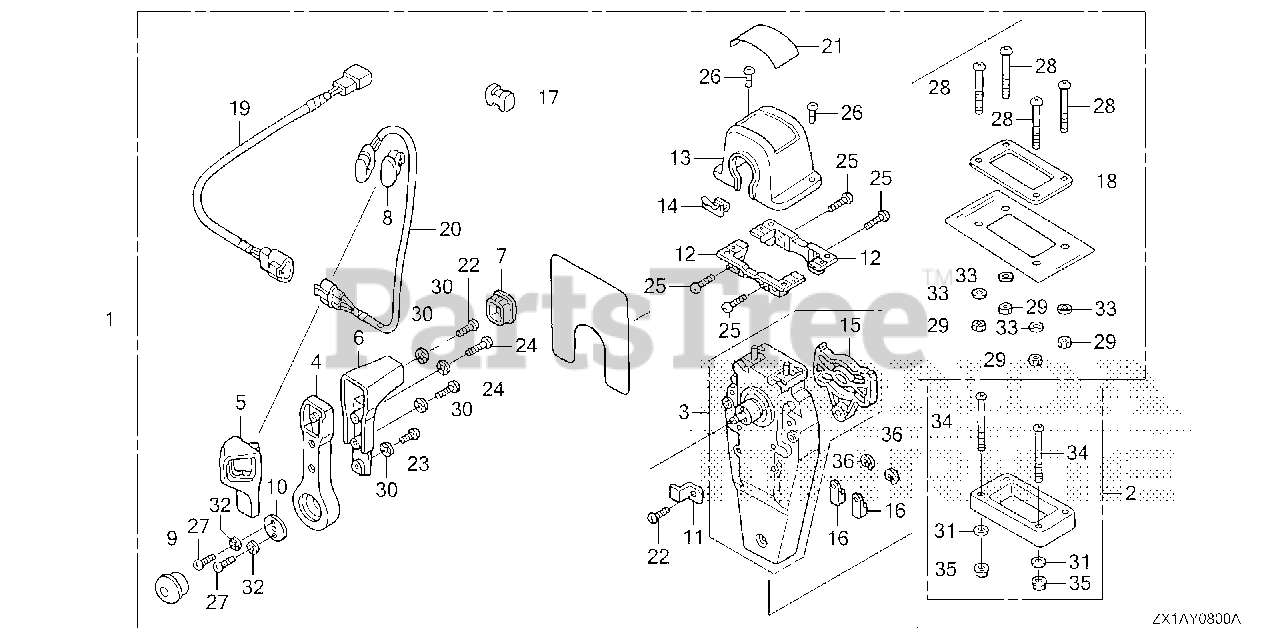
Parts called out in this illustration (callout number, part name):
1	BOX KIT, REMOTE CONTROL (TOP MOUNT SINGLE)(R)
2	SPACER KIT, REMOTE CONTROL BOX (TOP MOUNT SINGLE)
3	HOUSING ASSY., L. (INNER) (TOP MOUNT)
4	HANDLE, REMOTE CONTROL
5	COVER, L. GRIP
6	GRIP, REMOTE CONTROL HANDLE
7	CAP, GRIP
8	CAP, SWITCH
9	BUTTON, THROTTLE
10	PLATE, HANDLE
11	PLATE, CABLE CLAMP
12	BRACKET, REMOTE CONTROL HOUSING
13	HOUSING, REMOTE CONTROL BOX
14	HOUSING, LEAD
15	PLATE, DWELL
16	TERMINAL, CABLE
17	SPACER, CABLE CLAMP
18	GASKET, SINGLE
19	SUB-HARNESS ASSY., POWER TRIM-TILT (A)
20	SWITCH ASSY., POWER TRIM-TILT (A)
21	MARK, REMOTE CONTROL (SINGLE)
22	SCREW, PAN (5X16)
23	SCREW, PAN (5X10)
24	SCREW, PAN (5X20)
25	SCREW, PAN (5X18)
26	SCREW, PAN (4X10)
27	SCREW, PAN (6X18)
28	SCREW, PAN (5X40)
29	NUT, HEX. (5MM)
30	WASHER, LOCK (5MM)
31	WASHER, PLAIN (5MM)
32	WASHER, LOCK (6MM)
33	WASHER, PLAIN (5MM)
34	SCREW, PAN (5X65)
35	NUT, HEX. (5MM)
36	E-RING (6MM)
